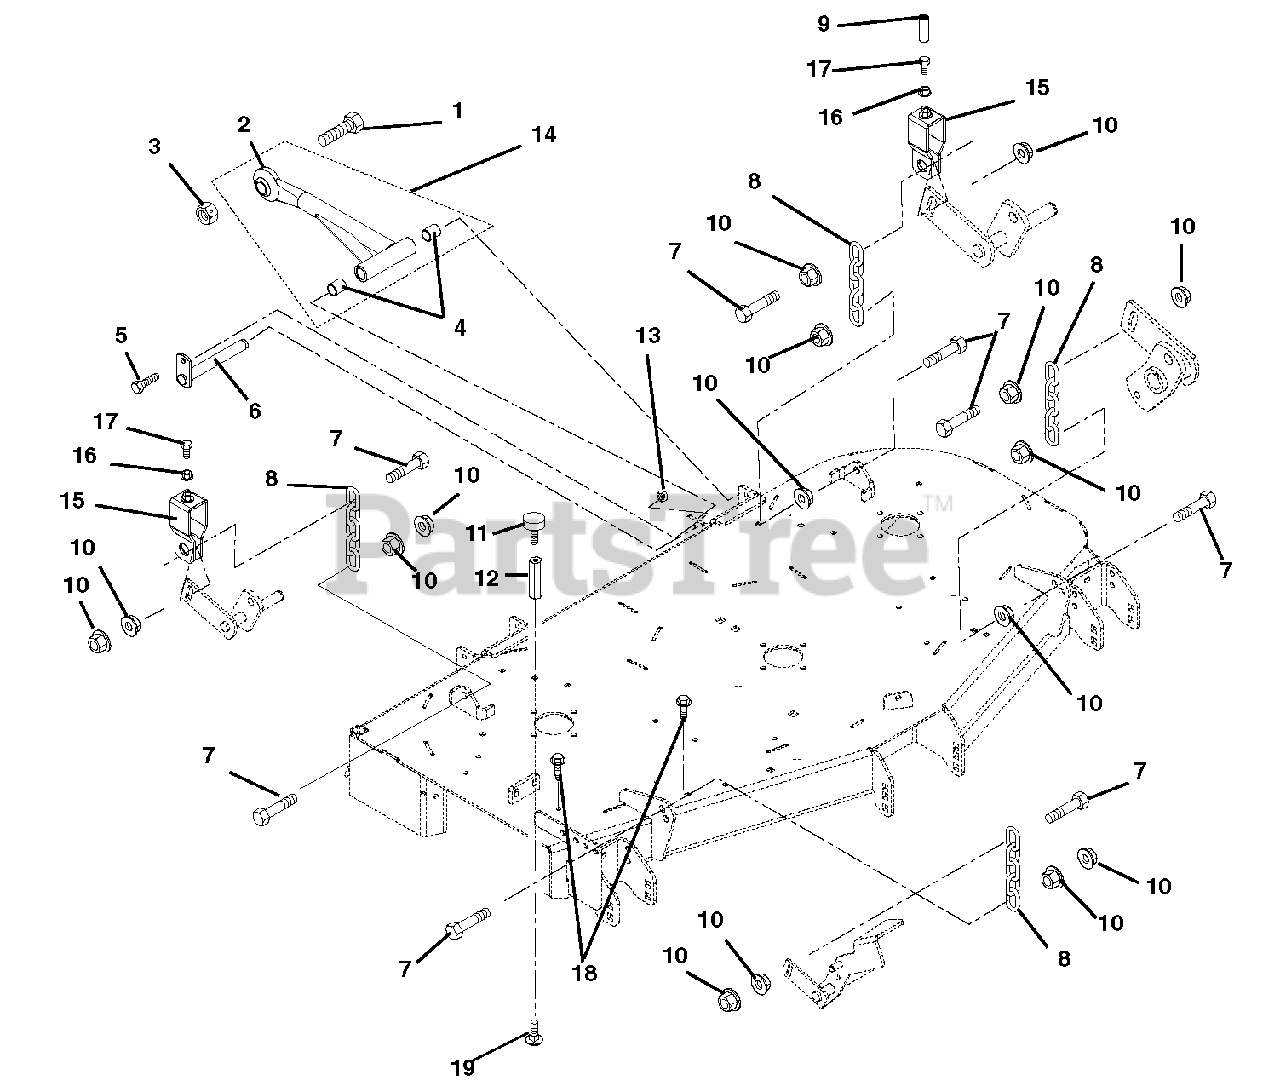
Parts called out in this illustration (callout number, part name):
1	Bolt, Hex .875-9 x 2.75 Grade 5
2	Mower Mounting Arm Weldment
3	Nut, Locking Center .875-9
4	Bearing, .75 x .875 x 1.00
5	Bolt, Hex .38-16 x 1.00 Grade 5
6	Weldment, Mower Mounting Pin
7	Bolt, Hex M12-1.75 x 50 Grade 5
8	Chain, Link
9	Cap, Vinyl .50 ID x 1.50LG x .055
10	Nut, Spin Lock Flange M12-1.75
11	Bumper, Rubber
12	Nut, Coupling .31-18 x 3.00
13	Nut, .38-16 Nyloc Flange
14	Assembly, Mower Mounting Arm (Includes item # 2 and item # 4)
15	Bracket, Deck Leveling
16	Nut, Jam .312-18
17	Bolt, Full Thread Hex .312-18 x 2.00
18	Screw, Tapping Hex Washer Head Thread .38-16 x .50 (188, 189, 190, 192)
19	Bolt, Round Head Square Neck .31-18 x .75
